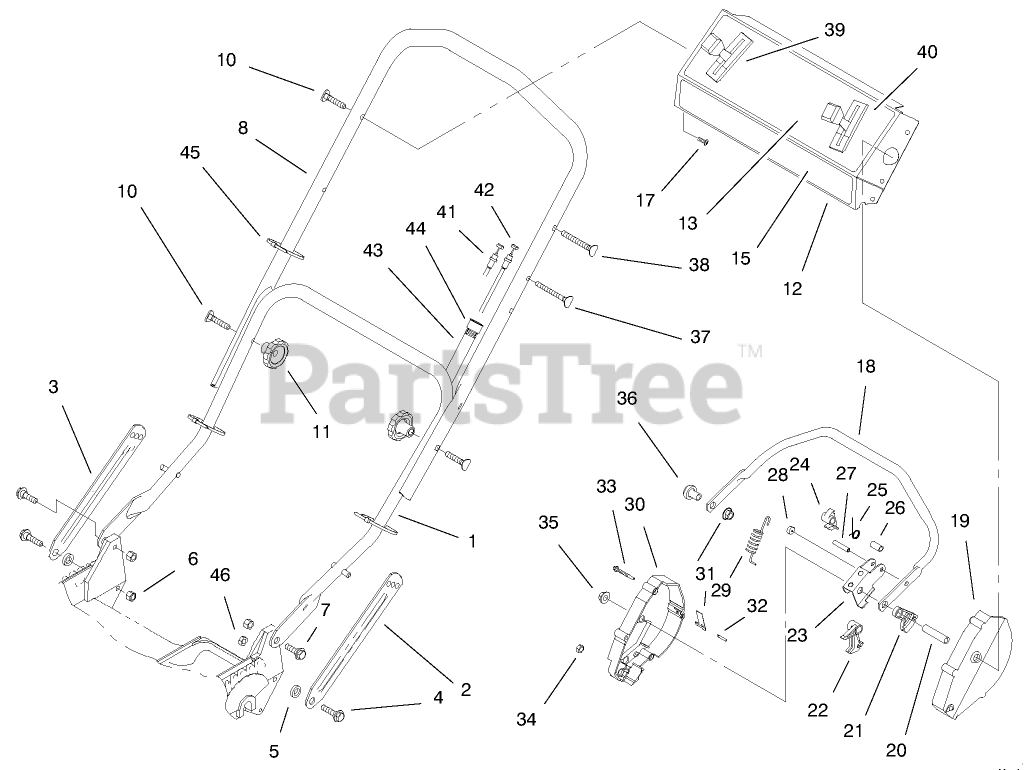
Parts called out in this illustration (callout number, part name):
4	SCREW-SHOULDER
5	SPACER
6	NUT-LOCK, NI
7	SCREW-SHOULDER
8	HANDLE - DIPPED
10	SCREW-HANDLE
12	PANEL W/DECAL
13	DECAL - INSRTUCTION
15	DECAL - CONSOLE
17	SCREW-TAP
20	TUBING-SPACER
21	LEVER-TRACTION
23	LEVER-CABLE
24	HOOK-CONTROL
25	SPRING-TORSION
26	SPACER
27	PIN-ROLL, SLOTTED
28	WASHER-NYLON
29	SPRING-DETENT
31	SPRING-LEAF
32	PIN-INSERT
33	SCREW-HWHTF
34	NUT-LOCK NI
36	SPACER-SUPPORT
37	SCREW-HANDLE
38	SCREW - HANDLE
39	CONTROL-SPEED, GROUND
40	THROTTLE CONTROL
41	CLUTCH CABLE
42	TRACTION CABLE
44	FITTING-RING
45	TIE-CABLE
46	NUT-LOCK, NI
